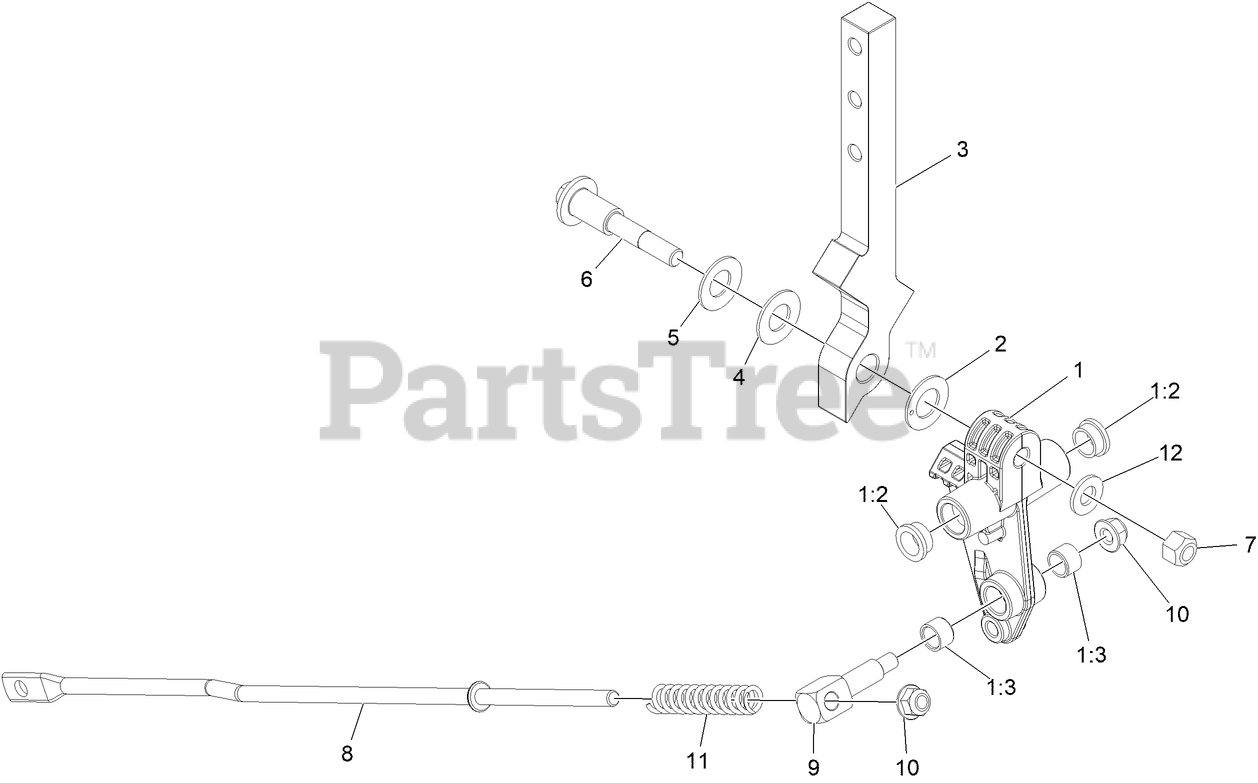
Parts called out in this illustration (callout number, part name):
1	CONTROL ARM ASM
1:2	BUSHING
1:3	BUSHING-SLEEVE
2	WASHER-FRICTION
3	ARM-CONTROL
4	WASHER
5	WASHER-BELLEVILLE
6	BOLT-PIVOT
7	NUT-LOCK, CONE
8	LINK-CONTROL
9	SWIVEL
10	NUT-HF, NI
11	SPRING-RETURN, NEUTRAL
12	WASHER-FLAT
